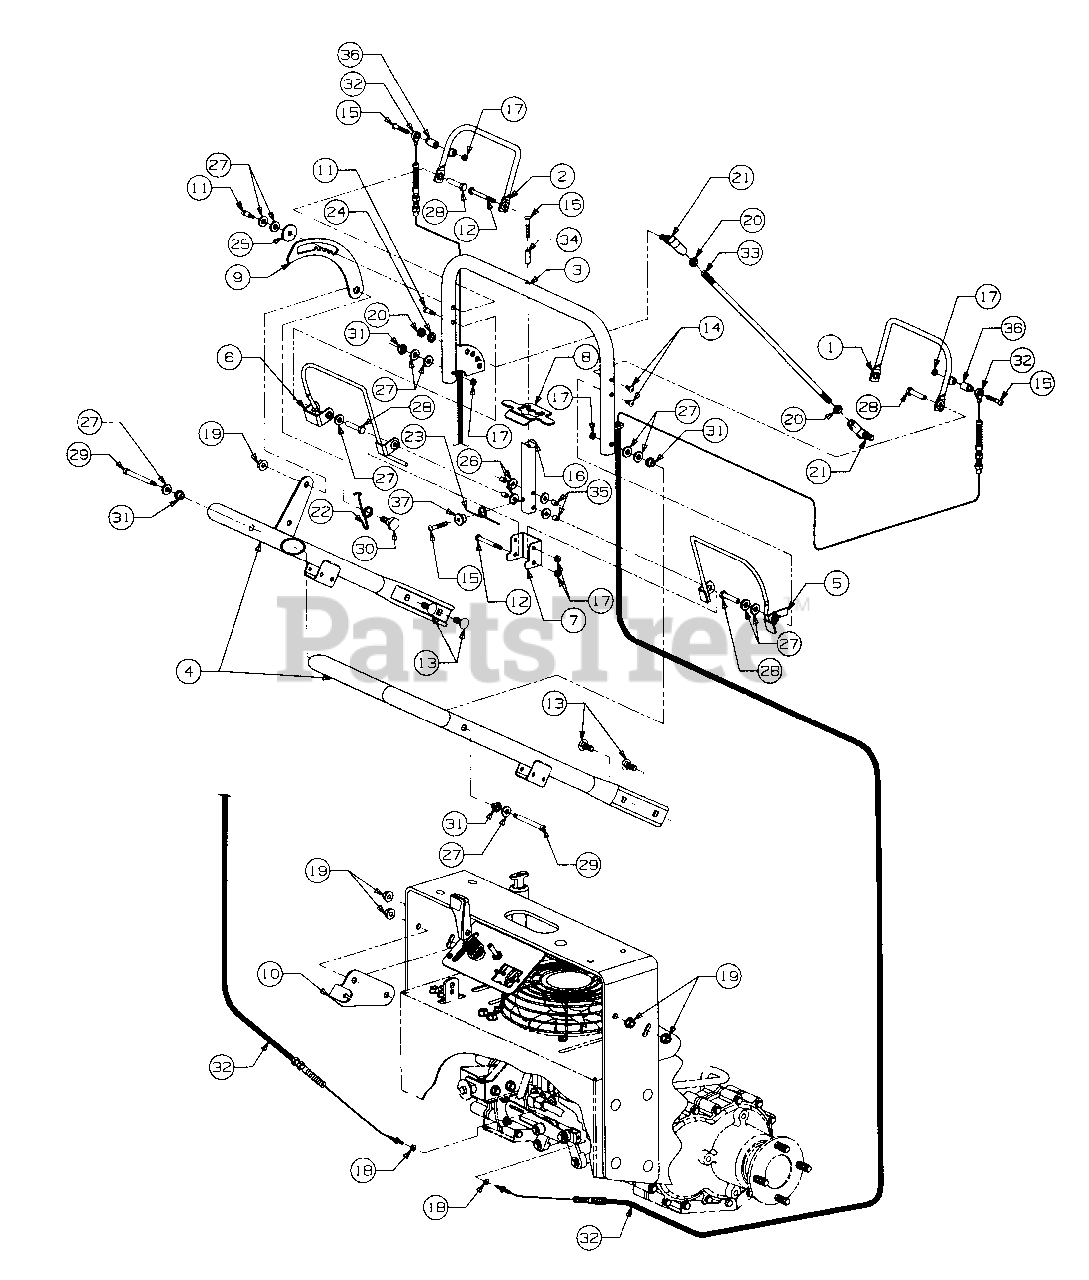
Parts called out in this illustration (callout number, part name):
1	Lever w/Bushings, R.H. Brake
2	Lever w/Bushings, L.H. Brake
3	Bar w/Graphics, Traction Control
4	Bar, Lower Handle
5	Lever w/Bushings, Operator-Present
6	Lever w/Bushings & Graphic, Speed Set
7	Stop, Handle
8	Latch w/Graphic, Park Brake
9	Plate, Speed Set
10	Bracket, Trans Release Cable Mtg
11	Screw, Socket Hd Shoulder
12	Screw, Hex Cap, 1/4-20 X 2.50 Lg GR5
13	Bolt, Carriage, 3/8-16 X 1.0 Lg GR5
14	Screw, Button Hd, 1/4-20 X .50 Lg
15	Screw, Button Hd, 1/4-20 X 1.50 Lg
16	Post, Park Brake
17	Nut, Hex Toplock, 1/4-20
18	Nut, Hex, #10-32
19	Nut, Hex Flanged Lock, 3/8-16
20	Nut, Hex Jam, 3/8-24 GR5
21	Ball Joint, 3/8-24
22	Spring, Torsion
23	Spring, Torsion
24	Washer, Lock, 3/8
25	Washer, Flat, .32 X 1.25 X .06 Thk
26	Washer, Flat, .281 X .75 X .105 Thk
27	Washer, Flat, .312 X .75 X .119 Thk
28	Bolt, Shoulder
29	Bolt, Socket Hd Shoulder
30	Bolt, Stepped Shoulder
31	Bushing, Nylon
32	Cable, Brake Clutch
33	Rod, F/R Control
34	Spacer, 5/16 OD X 1/4 ID X .94 Lg
35	Spacer, 5/16 OD X 1/4 ID X .375 Lg
36	Spacer, Cable
37	Spacer, Spring Mtg
